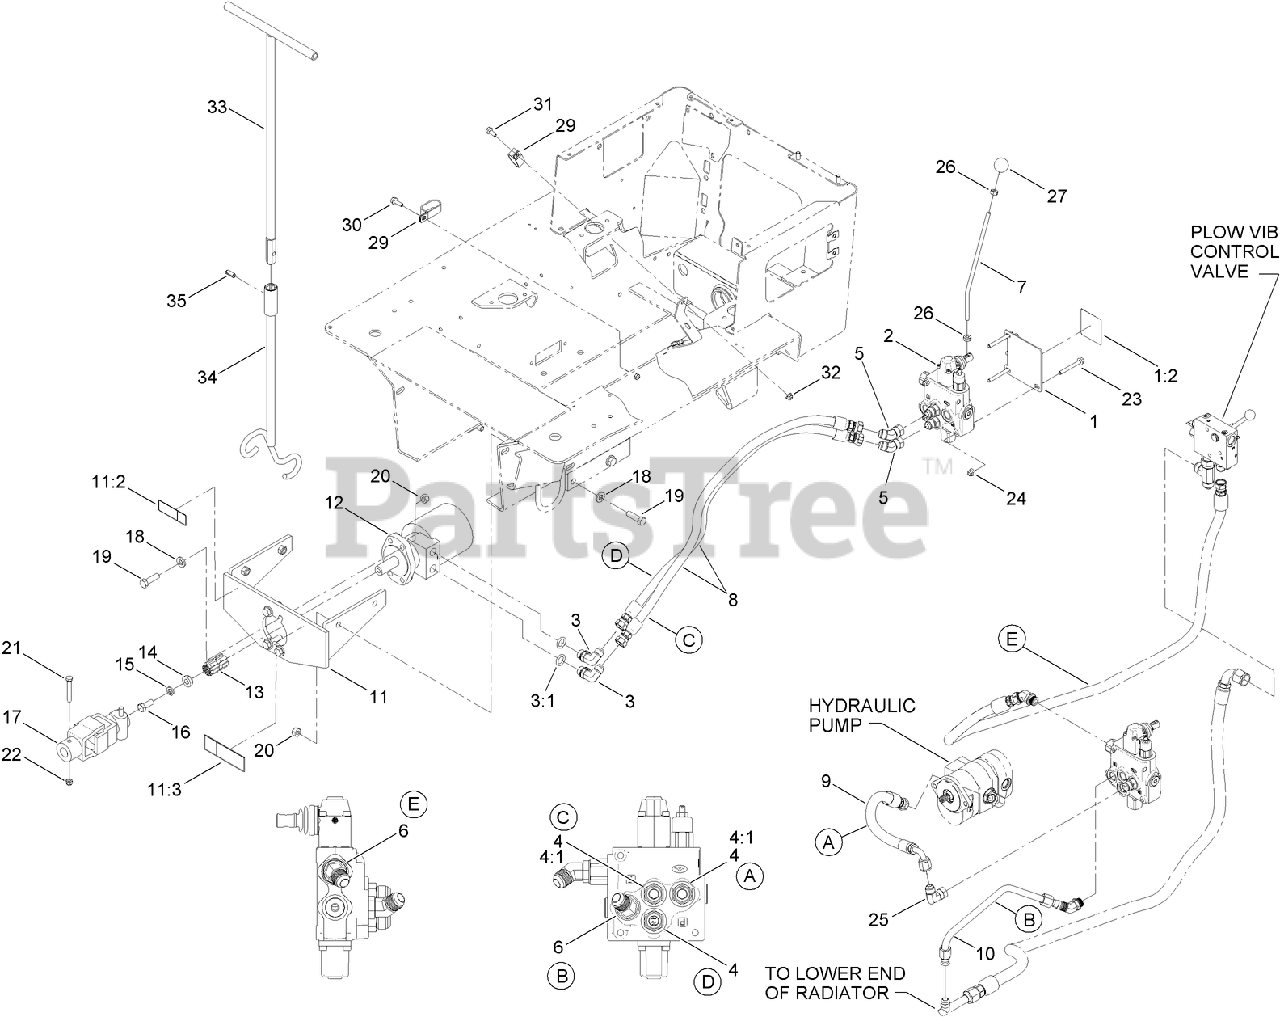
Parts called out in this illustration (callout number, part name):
1	HYDRO VALVE BRACKET ASM
1:2	DECAL-HYDRABORE DIRECTION
2	HYDRO VALVE ASM
3	FITTING-ELBOW, 90 DEG
3:1	O-RING
4	FITTING-STRAIGHT
4:1	O-RING
5	FITTING-ELBOW, 45 DEG
6	FITTING-ELBOW, 45 DEG
8	HYD HOSE ASM
9	HYD HOSE ASM
10	HYD TUBE ASM
11	MOUNT ASM
11:2	DECAL-DANGER
11:3	DECAL-DANGER, ENTANGLEMENT
12	HYD MOTOR ASM
13	ADAPTER
14	RETAINER-ADAPTER
15	WASHER-LOCK
16	SCREW-HH
17	U-JOINT ASM
18	WASHER-FLAT
19	SCREW-HH
20	LOCKNUT
21	SCREW-HH
22	NUT-HEX
23	SCREW-HHF
24	NUT-LOCK, HHF
25	ADAPTOR
26	NUT-HEX
27	KNOB-ROUND
29	CLAMP-R, DOUBLE
30	SCREW-HHF
31	SCREW-HHF
32	NUT-HF, NI
33	HANDLE-TOOL, GUIDE
34	TOOL-GUIDE, ROD
35	PIN-ROLL
